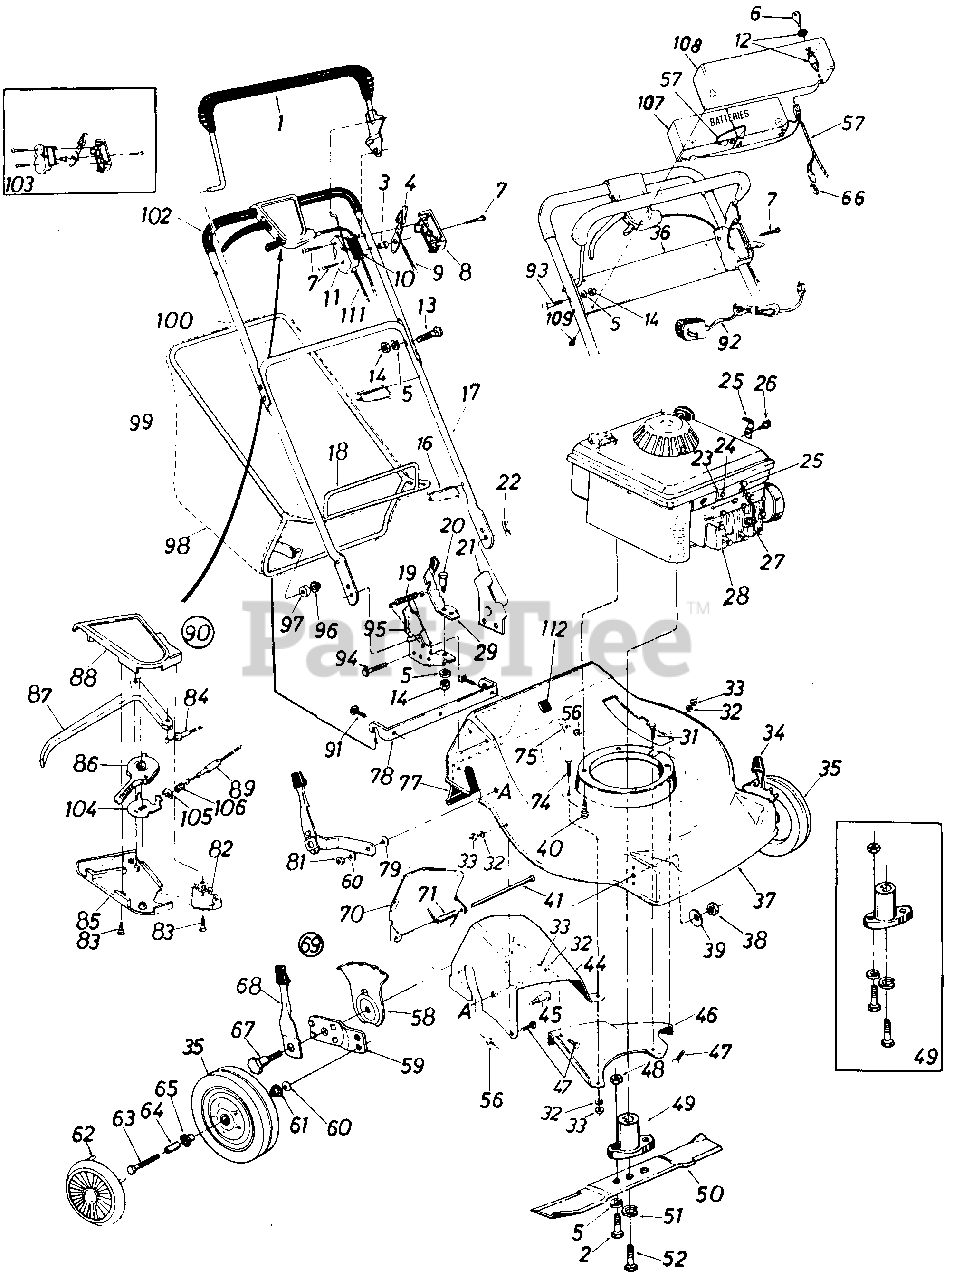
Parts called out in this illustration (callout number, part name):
2	SCREW-HEX SPECIAL 5/16-24X1.0
3	PIN-CONTROL DISC
4	LEVER-THROTTLE CONT-REV
5	WASHER-LOCK-5/16
6	KEY-IGN (SET OF TWO)
7	SCREW-TRUSS MACH
8	PANEL HALF-CONTROL
9	WIRE-THROTTLE 58 LG
11	PANEL HALF-CLUTCH
12	SWITCH-KEY
13	BOLT-CARRIAGE 5/16-18 X 1.75
14	NUT-HEX 5/16-18
16	TIE-CABLE
17	HANDLE-LOWER PAINTED
20	SCREW-SHLD .437 DIA X .162
21	BRACKET-HANDLE-RH
22	PIN-INTERN COT-5/16 DIA
23	CLAMP-CASING
24	SCREW-HEX WASH HD TAP
25	CLAMP-CASING
26	SCREW-HEX B-TAP #10 X .38
27	INSULATOR-SPARK PLUG
29	LEVER-LOCK
31	SCREW-HEX HD TAP 1/4-20 X 7.5
32	LOCK WASHER 1/4 DIA
33	NUT-HEX 1/4-20
34	ADJUSTER ASSY-HGT-LH
35	WHEEL ASSY
36	TRAY-BATTERY-LOWER
39	WASHER-BELL .390 ID X 1.375 X .062
40	SCREW-HEX R
41	PIN-HINGE
44	BAFFLE-CHUTE-RR-RH
45	SCREW-SHLD .500 DIA X .685
46	BAFFLE-CHUTE-RR-LH
47	BOLT-CARRIAGE 1/4-20 X .50
48	NUT-5/16-24
49	KIT-BLADE ADAPTER
50	BLADE-22IN
51	SCREW-HEX 3/8-24 X 2.25
52	SCREW-HEX 3/8-24 X 2.25
56	NUT-SEMS 1/4-20
57	WIRE HARNESS
58	PLATE-HGT ADJ R
59	BAR-PIVOT R
60	WASHER-BELL .400 ID X .88 X .060
61	BEARING-FLANGE
62	HUB CAP-BLACK
63	SCREW-HEX 3/8-16 X 1.75
65	BEARING-BALL
66	PLUG
67	SCREW-SHLD R
68	LEVER & KNOB ASSY
69	ADJUSTER ASSY-HGT-RH
70	DOOR-CHUTE
71	SPRING-TORSION
74	SCREW-HEX 1/4-20 X .88
75	WASHER-FL-.285 ID X 1.25 OD X .060
78	ADAPTER-GRASSCATCHER
79	WASHER-BELL .3/8ID X 1.12OD X .030
81	NUT-HEX JAM 3/8-18
82	CAP-CABLE MTG
83	SCREW-FL C-SUNK AB
84	CABLE-CLUTCH
85	COVER-LOWER
86	LEVER-3 SP SHIFT
87	LEVER-CONTROL
88	COVER-UPPER
89	CABLE-SHIFT
90	KIT-CLUTCH HSG
91	BOLT-CARRIAGE 1/20 X .75
92	CHARGER-BATTERY
93	BOLT-CARRIAGE-CURV 5/16-18 X 1.38
94	SCREW-HEX 1/4-28 X .75
95	BRACKET ASSY-HDLE-RH
97	ROLLER-PLASTIC
98	BAG-GRASS
99	FRAME-CATCHER-UPR
100	HANDLE-UPPER-CHROME
102	GRIP-SHRINK-25 IN
103	KIT-THROTTLE CONTROL
105	BRACKET-SPRING
106	SPRING-MTG
107	KIT-BATTERY-MOWERS
108	TRAY-BATTERY
109	SCREW-TAP .215 X 1
111	CABLE-CONTROL
